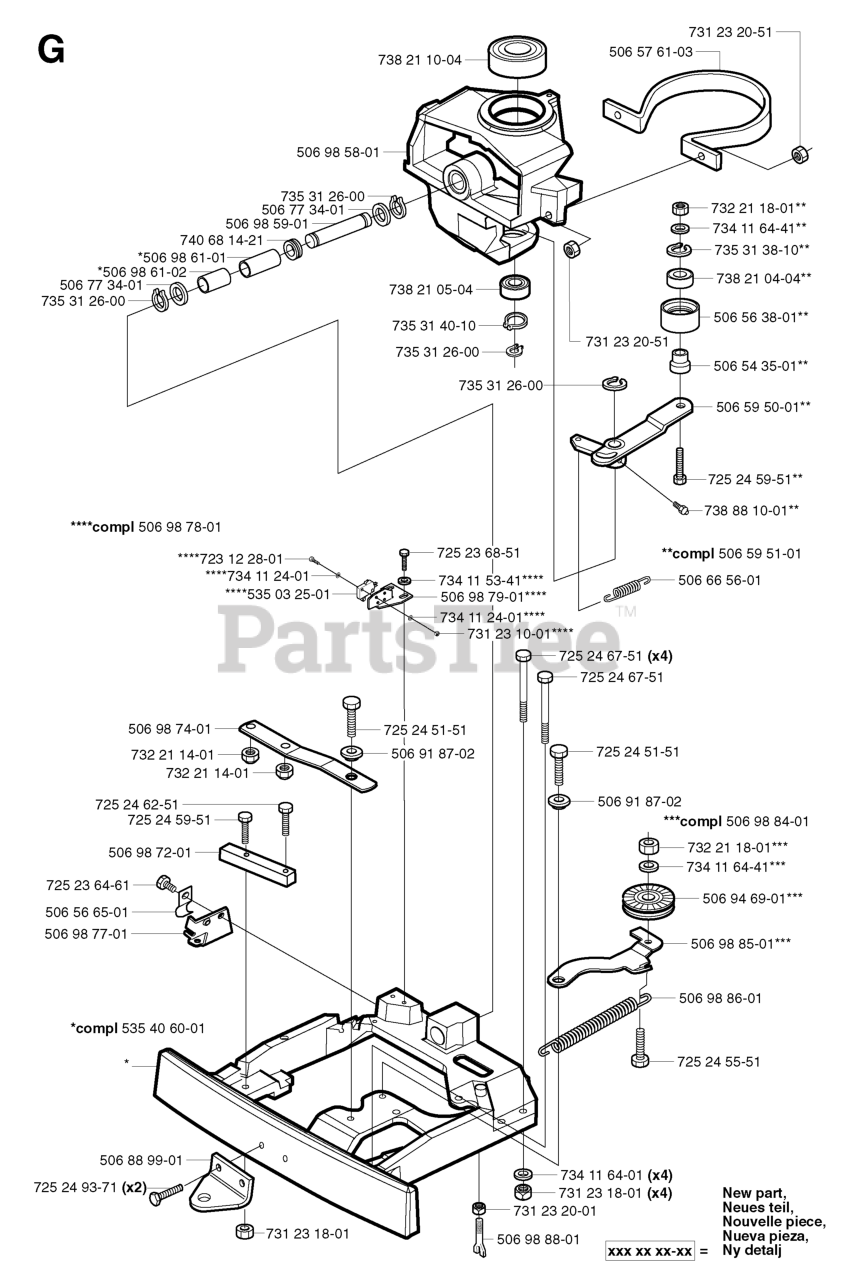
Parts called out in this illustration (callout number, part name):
2	GASKET, BASE
5	GASKET, INSULATOR
6	GASKET, CARB (RPLS T155113131)
10	AIR CHECKER (S) ASSY
14	PIPE AIR (S)
15	AIR CHECKER (F) ASSY
19	PIPE AIR (F)
20	GASKET, VALVE
22	CRANKCASE-C
24	GASKET.CASE
25	BEARING
34	PIN (RPLS T151341310)
38	CRANKSHAFT COMP(RPLS481042000)
39	NUT
44	CAP
47	CARBURETOR WYA-138
48	REBUILD KIT
49	CARBURETOR BODY
50	GASKET KIT
58	NUT
59	SCREW CABLE ADJUST
82	PLATE, MUFFLER
84	COVER COMP
86	DRUM (RPLS 481031120-22)
90	BRACKET(A)-24
91	BRACKET(B)-24
96	COVER ENGINE
98	BOLT 08
107	CORD.EARTH
108	TUBE (RPLS 263072210)
109	SPARK PLUG NGK CMR7H
112	REEL
114	SPRING, SPIRAL
119	PLATE.STOPPER
121	BOLT M5X14
124	PLATE, CHOKE
127	ELEMENT
128	COVER ASSY
130	TANK-A
136	PIPE-C
137	FILTER
140	LABEL RECOIL
147	BOLT
150	TOOL SET (RPLS 848-8UD-0120)
152	SOCKET
